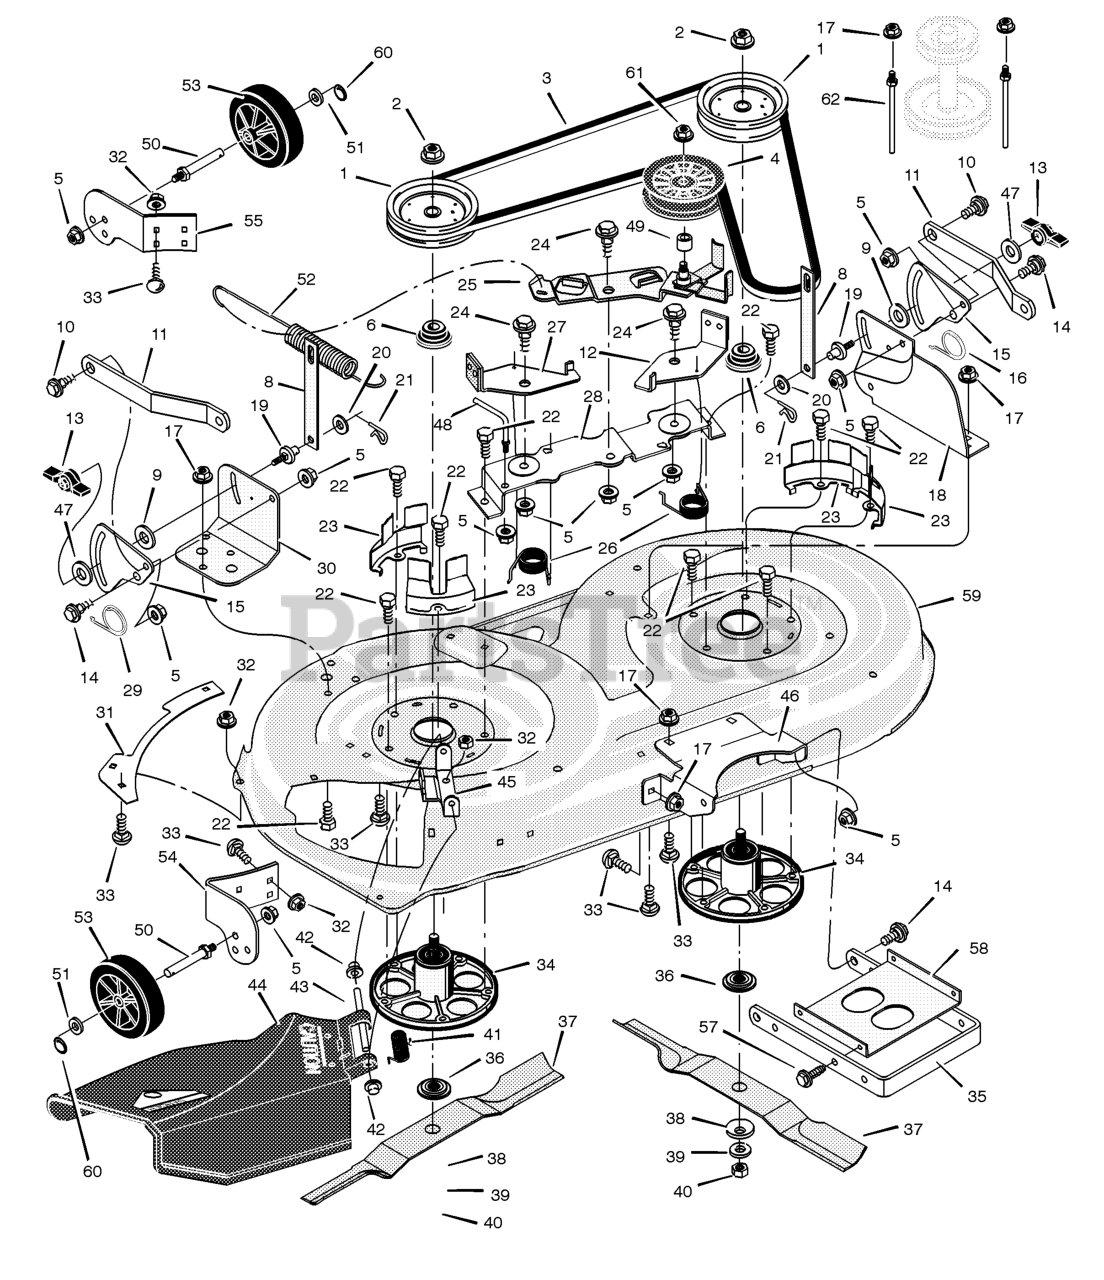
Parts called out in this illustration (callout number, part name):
1	Pulley, Jackshaft
2	Nut, Hex
3	Belt, Mower Drive
4	Pulley, Idler
5	Nut, Flange
6	Spacer, Pulley
8	Link, Lift
9	Pad, Friction
10	Bolt, Shoulder
11	Bracket, Suspension
12	Pad Assembly, Left Brake
13	Knob
14	Bolt, Shoulder
15	Plate, Suspension
17	Nut, Flange
18	Bracket, Suspension
19	Pin, Hanger
21	Pin, Hair
22	Bolt
23	Cover, Pulley
24	Bolt, Shoulder
25	Arm, Idler
27	Pad Assembly, Right Brake
28	Bracket, Brake
30	Bracket, Suspension
32	Nut, Flange
33	Bolt, Carriage
34	Mandrell Housing
35	Bracket, Suspension
36	Adapter, Blade
42	Cap, Push On
43	ROD, Deflector
44	Deflector Assembly
45	Bracket, Deflector Hinge
46	Bracket, Front Hanger
48	Guide, Belt
50	BOLT, Gauge Wheel
52	Spring, Extension
53	Wheel, Gage
54	Bracket, Right Wheel
55	Bracket, Left Wheel
58	Stiffener
59	Housing, Blade
60	Ring, Locking
61	Nut, Flange
62	Guide, Belt
